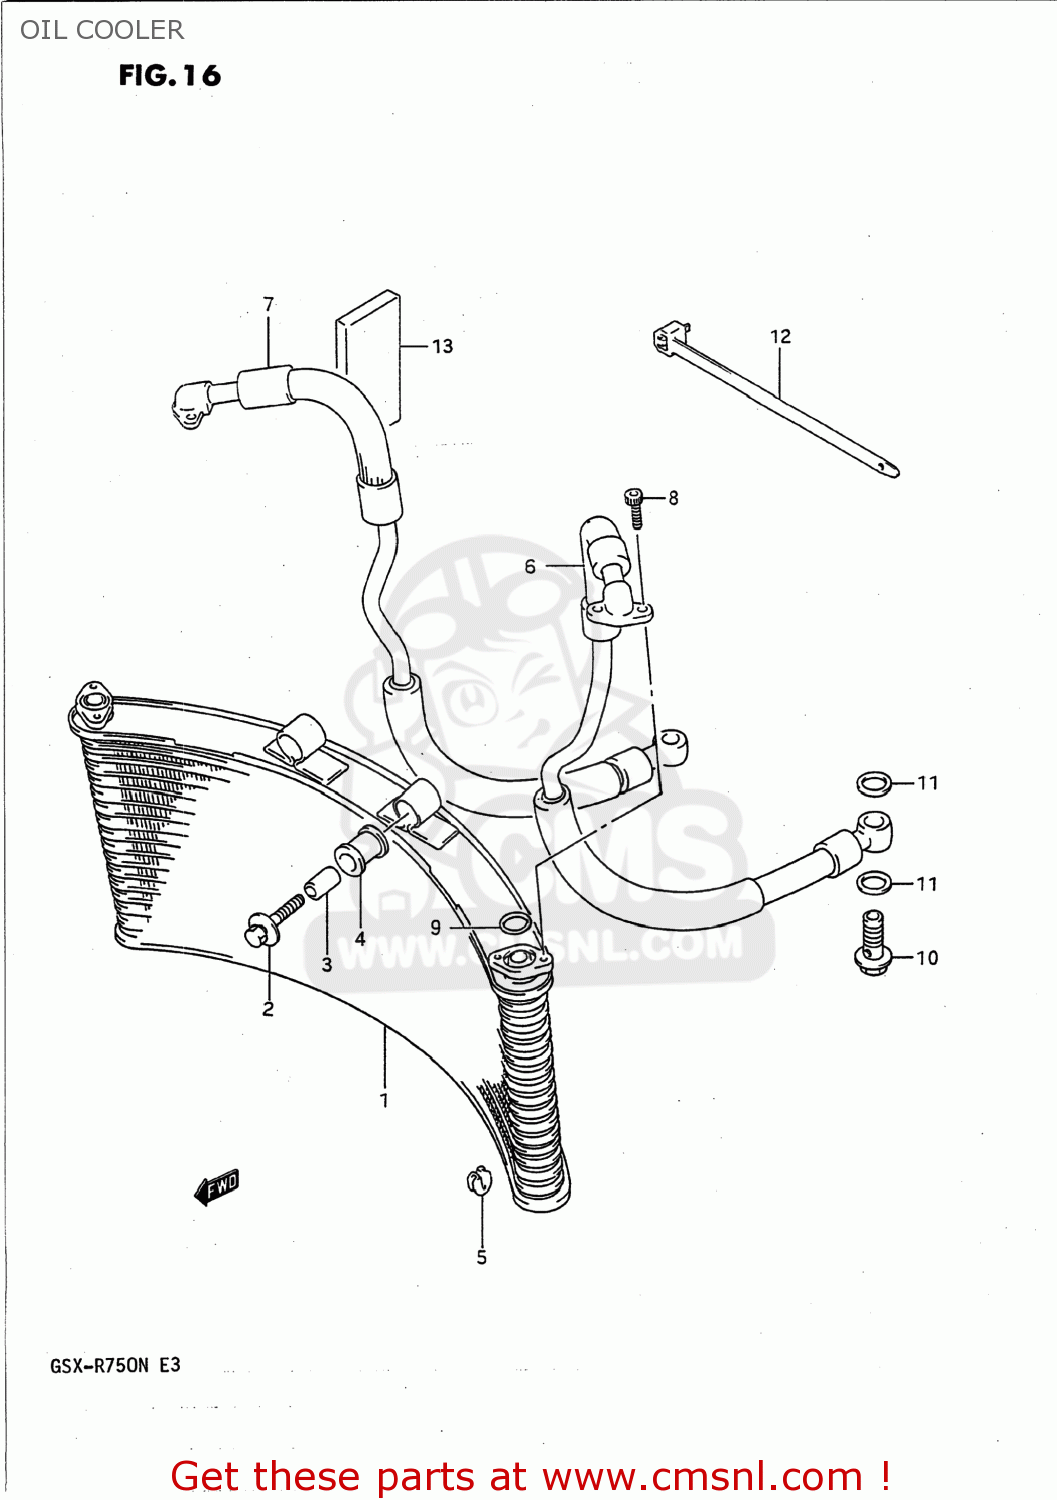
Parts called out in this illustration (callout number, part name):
1	COOLER ASSEMBLY,OIL
2	BOLT(8X40)
3	SPACER (8.8X12X24.5)
4	CUSHION,OIL COOLER NO.1
5	CUSHION,OIL COOLER NO.2
6	HOSE,COOLER,L
7	HOSE,OIL COOLER,R
8	BOLT
9	O RING(D:2.4,ID:12.3)
10	BOLT UNION
11	GASKET(16X22X2) (NAS)
12	CLAMP
13	PROTECTOR
